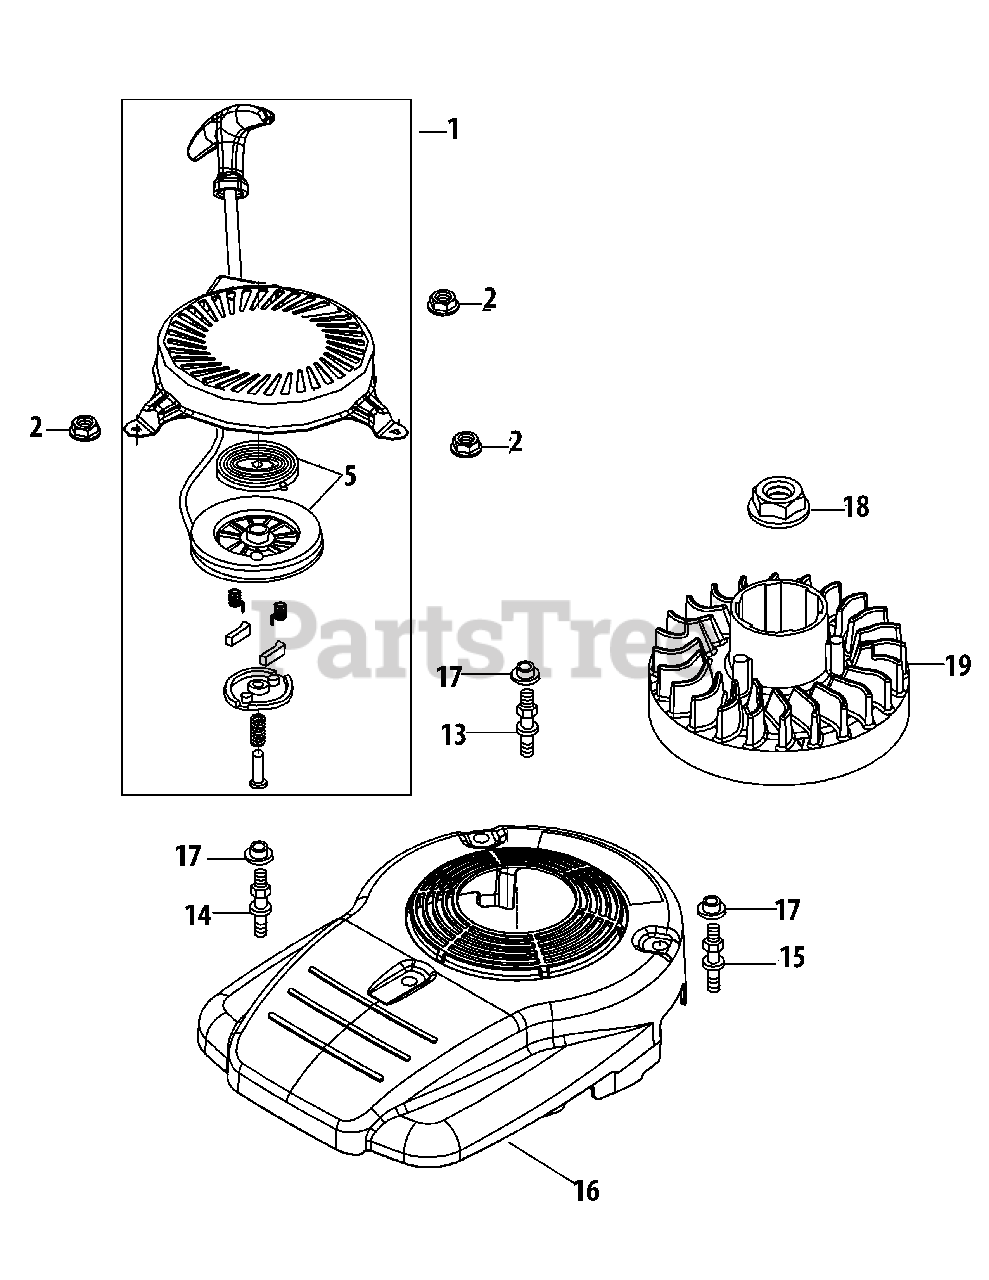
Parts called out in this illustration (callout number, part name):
1	Recoil Starter Assembly
2	Nut M6X10M
5	Recoil Pulley & Spring Assy
13	Shroud Stud Left/Black
14	Shroud Stud Front/Unmarked
15	Shroud Stud Right/White
16	Engine Shroud (M0)
17	Engine Shroud Spacer
18	Flywheel Nut M14
19	Flywheel
